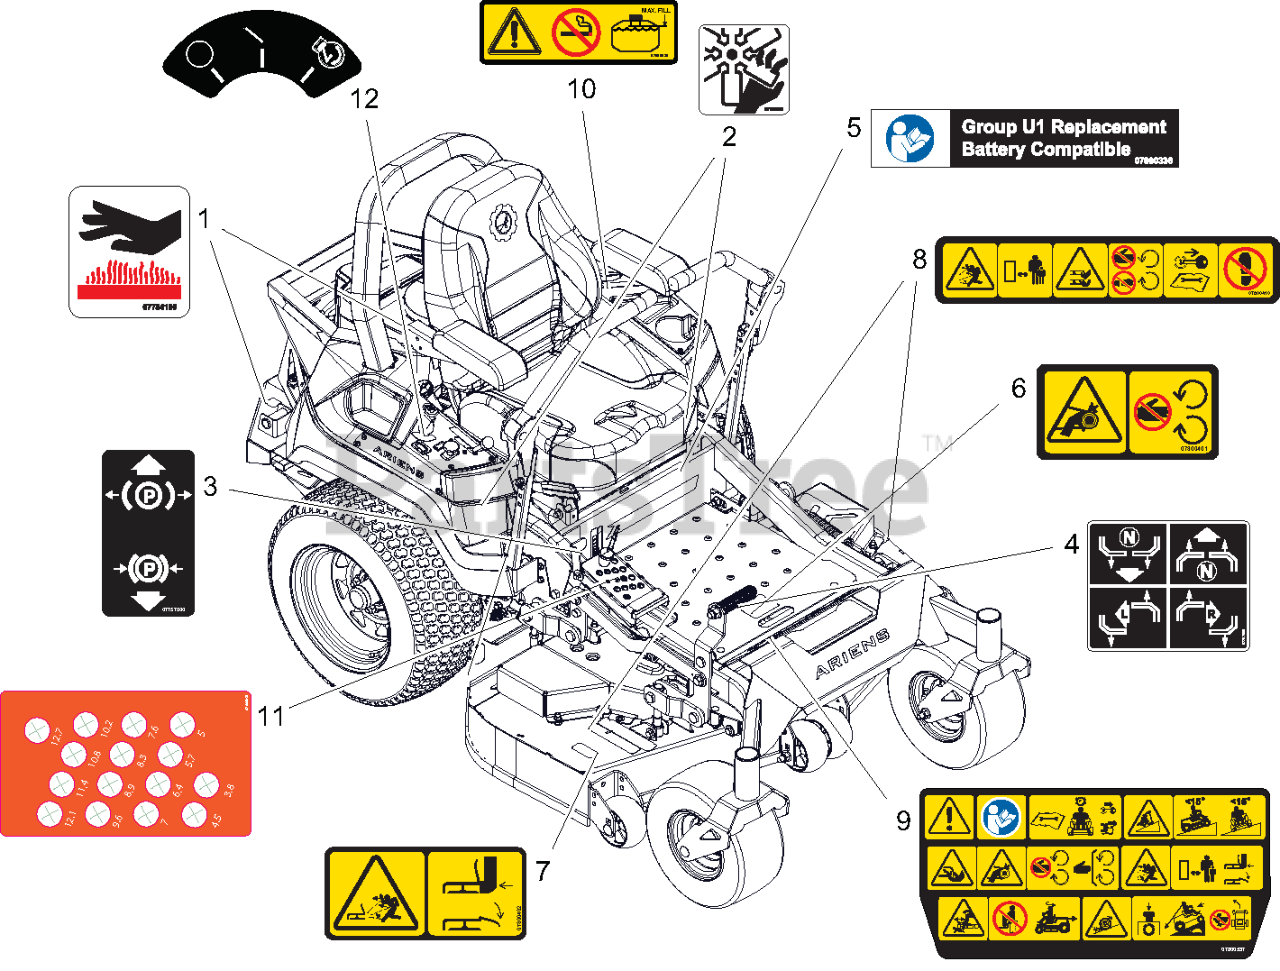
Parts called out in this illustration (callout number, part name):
1	DECAL, HOT SURFACE
2	DECAL, DANGER FAN
3	DECAL, PARKING BRAKE LEVER
4	DECAL, INSTRUCTIONAL-STEERING
5	DECAL, U1 BATTERY REPLACEMENT
6	DECAL, SAFETY - GUARDING
7	DECAL, SAFETY - DECK GUARDING
8	DECAL, DECK SAFETY
9	DECAL, MAIN SAFETY
10	DECAL, FUEL WARNING
11	DECAL, APEX HOC METRIC
12	DECAL, KEYSWITCH
